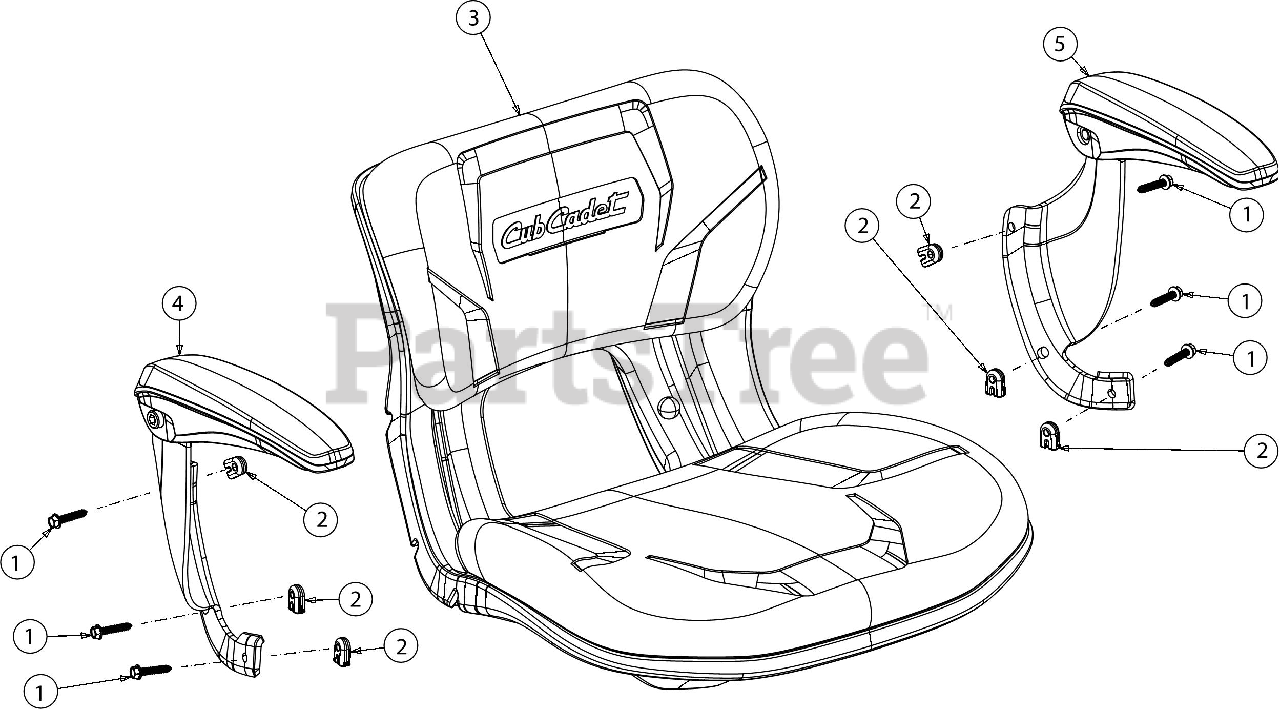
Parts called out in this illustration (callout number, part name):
1	SCREW 1/4-14X 1.25
2	ARMREST NUT
3	SEAT-CUB WHITE LOGO
4	ARM REST KIT
5	ARM REST KIT
